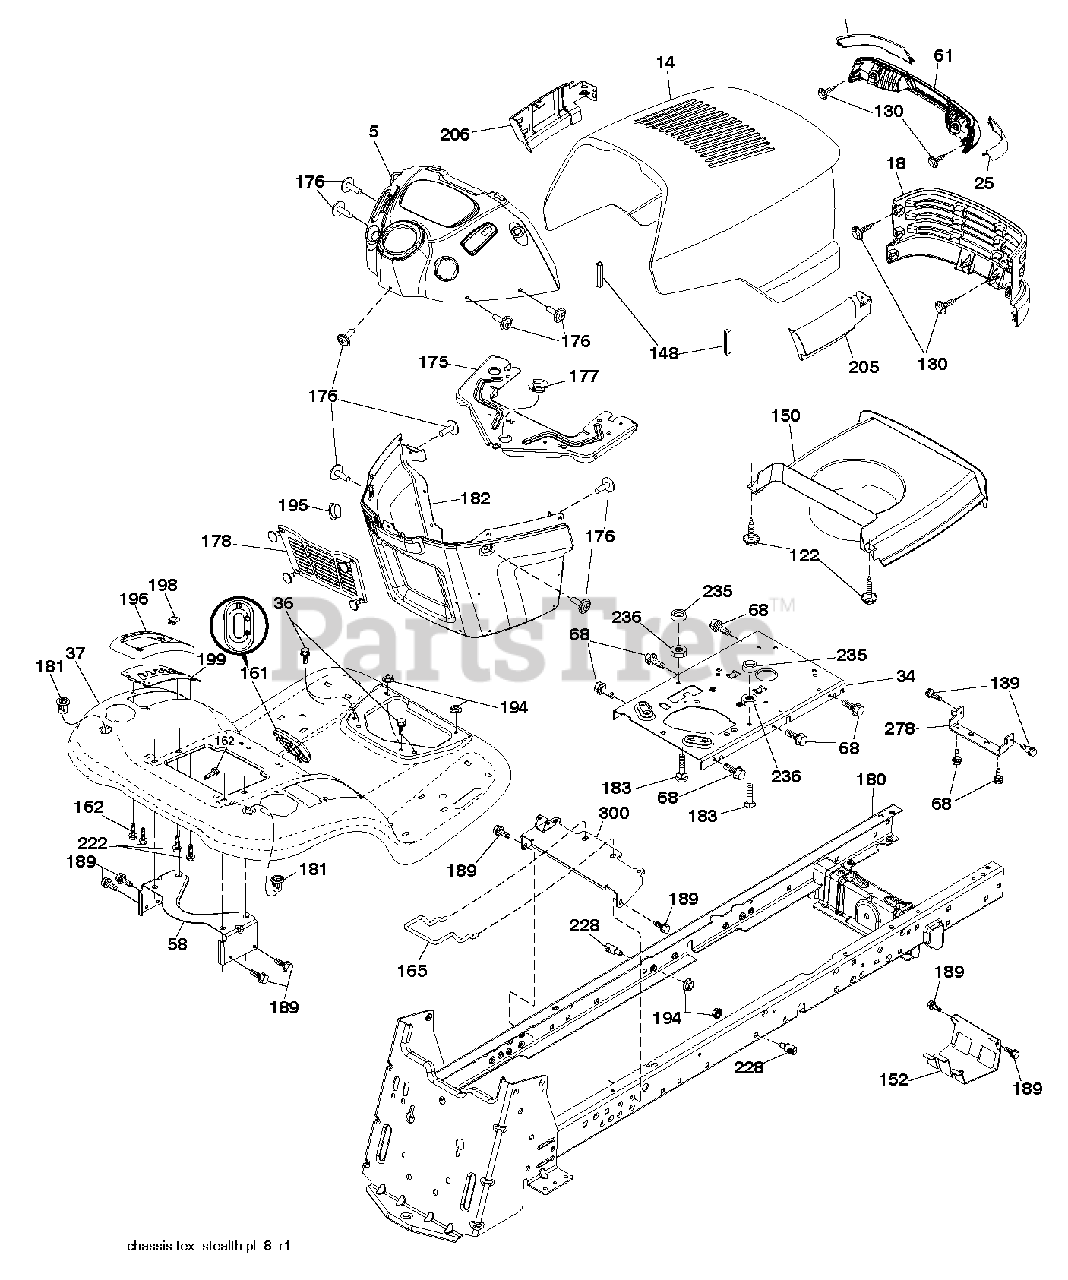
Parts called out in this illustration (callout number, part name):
5	DASH.STEALTH.EL.LIFT.RND.428
14	HOOD ASM, PNT DIXON
15	LENS LH
25	LENS RH
34	PLATE.ENGINE.WELDED.CH
37	FENDER.PNT.TXGT.ERGO.SD.FILL
58	BRKT.SUPPORT.FNDR/TANK
61	LIGHTBOX.ASM.STEALTH.DL.DIXON
68	SCREW LT
130	SCREW.#10 X 0.750.BOS THREAD
148	EXTRUSION BUMPER
150	DUCT HEAT HOOD
152	SHIELD BROWNING
165	SUPPORT.TANK.REAR.B/TE
175	CROSSMEMBER.
176	SCREW.#10-24X5/8.RN.QU
177	BUSHING,STEERING
178	CARGO.ASM.NET.DASH.LOWER
180	CHASSIS
182	DASH.LOWER.
183	BOLT.5/16-18X1-1/4 FULL THD
194	NUT LOCK HEX FLANGE 5/16-18
196	CONSOLE.ASM.DECK.
198	INDICATOR DECK LIFT
199	PLATE.DECK.LIFT.ELECTRIC
205	SKIRT.GRILLE.STEALTH.RH
206	SKIRT.GRILLE.STEALTH.LH
222	SCREW 1/4-20X5/8
228	STUD.FASTNER.W/ANTI-ROTATE
235	SPACER FENDER
236	JAM LOCK NUT
278	BRKT.HOOD/MUFF.STEALTH
300	BRACKET.ASM.LIFT.ELECTRIC
